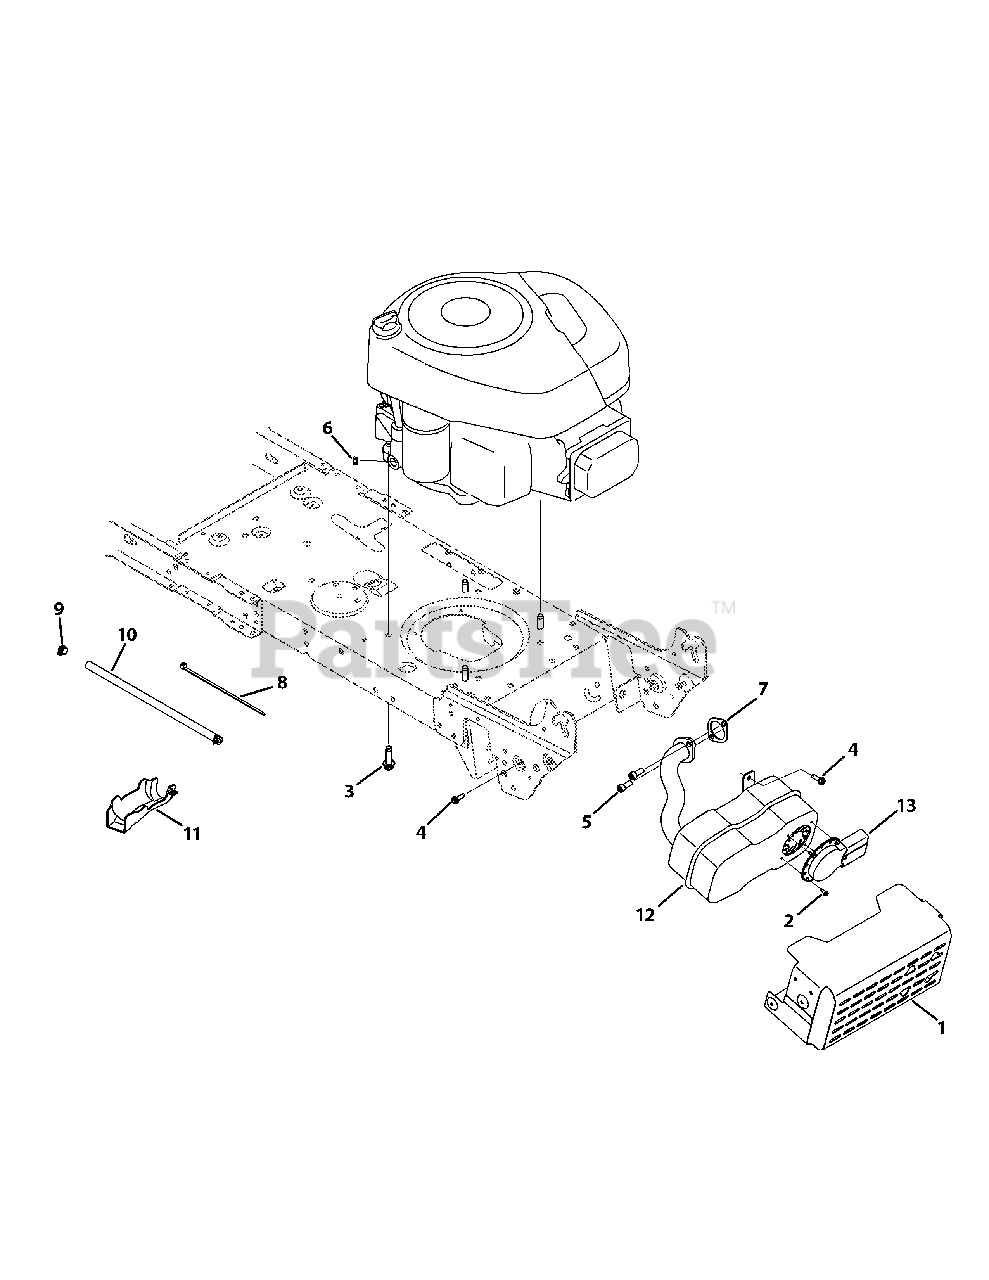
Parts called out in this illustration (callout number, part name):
1	Muffler Shield Assembly
2	Screw, 8-18 x .500
3	Screw, 3/8-16 x 1.0
4	Screw, 1/4-20 x .750
5	Socket Screw, 5/16-18 x .750
6	Sems Nut, 1/4-20
7	Exhaust Gasket, 10 HP Briggs
8	Cable Tie
9	Clamp Hose, .490 diameter
10	Fuel Hose, Low Permeation
11	Oil Drain Sleeve
12	Muffler, Single Inlet
13	Muffler Deflector Long
